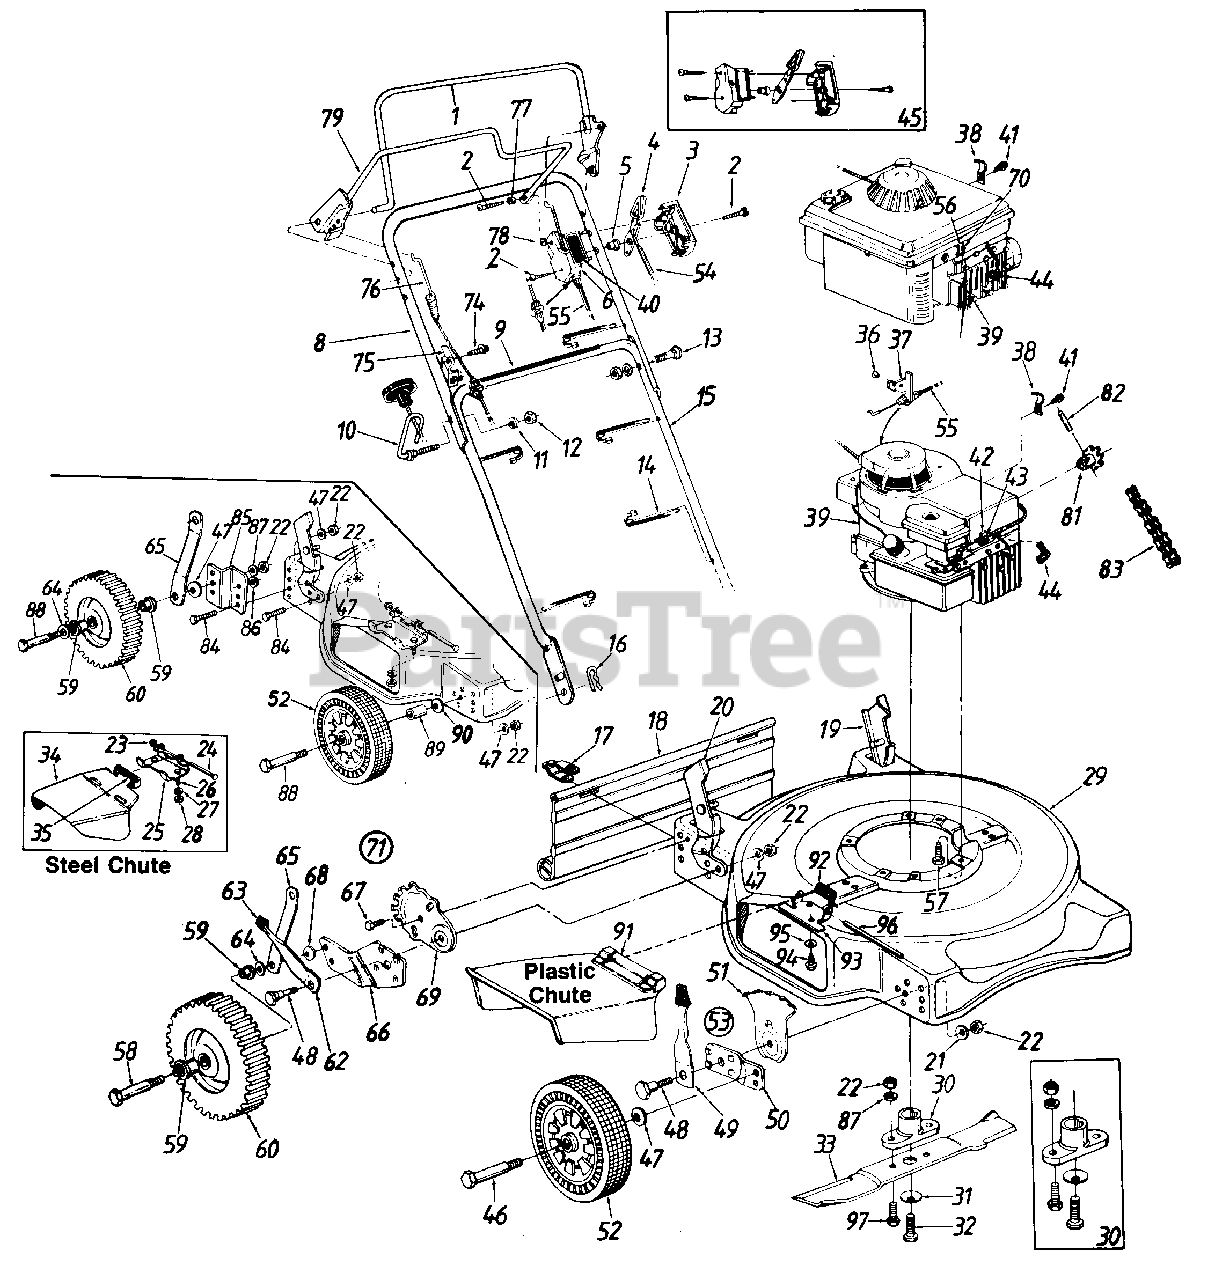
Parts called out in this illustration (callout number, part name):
1	Control Handle Ass'y.
2	Truss Mach. Scr. #12 x 1.5'
3	Control Panel Half
4	Throttle Control Lever
5	Control Disc Pin
6	Clutch Panel Half
8	Upper Handle (Painted)
9	Instruction Label-Handle
10	Rope Guide Bolt
11	L-Wash. 5/16" I.D.
12	Hex Nut 5/16-18 Thd.
13	Curved Carriage Bolt 5/16-18 x 1.38" Lg.
14	Cable Tie
15	Lower Handle (Painted)
16	Hairpin Cotter
17	Hinge Clip
18	Rear Flap
19	Handle Bracket Ass'y.-L.H.
20	Handle Bracket Ass'y.-R.H.
21	Bell-Wash. .39" I.D. x 1.38"
22	Hex Nut 3/8-16 Thd.
23	Push Cap 1/4" Rod
24	Pivot Pin
25	Adapter Plate
26	Hex Bolt 1/4-20 x .50" Lg.
27	L-Wash. 1/4" I.D.
28	Hex Nut 1/4-20 Thd.
29	22" Deck Ass'y.
30	Blade Adapter Kit
31	Bell-Wash. .39" I.D. x 1.12" O.D.
32	Hex Bolt 3/8-24 x 1.5" Lg.
33	22n Blade
34	Chute Deflector Ass y.
35	Torsion Spring
36	Pop Rivet
37	Cable Bracket
38	Cable Clamp
39	Engine
40	Throttle Label
41	Hex B-Tap Scr. #10 x .38"
42	Cable Clamp
43	Hex AB-Tap Scr. #8 x 88n Lg.
44	Spark Plug Boot
45	Kit-Control Housing Comp.
46	Front Axle Bolt
47	Bell-Wash. .400" I.D. x .881'
48	Shld. Bolt .50" Dia. x .357"
49	Spring Lever Ass'y. w/Knob
51	Height Adj. Plate
52	Wheel Ass'y. Comp.
53	Height Adj. Ass'y. Comp.-R.H.
54	Throttle Wire-53"
55	Control Cable-39"
56	Cable Clamp
57	Hex L-Wash. HD. Scr. 3/8-16 x 1.0" Lg.
58	Rear Axle Bolt
59	Fl. Ball Brg. 1/2" I.D.
60	Rear Wheel Ass'y. Comp.
62	Spring Lever
63	Spring Lever Knob
64	Fl-Wash. .531" I.D. x .93"
67	Hex AB-Tap 1/4-.62" Lg.
68	Bell-Wash. .380" I.D. x .88"
69	Index Plate
70	Hex B-Tap Scr. #10 x .62"
71	Rear Height Adj. Ass'y.-R.H.
74	Hex Wash. AB-Tap Scr. 5/16 x.75" Lg.
75	Cable Brkt.
76	Clutch Cable w/Spring-33"
77	Spacer 23" I.D. x .30" O.D.
78	Spr.-Wash. .206" I.D. x .448
79	S.P. Bail Ass'y.
81	10 Tooth Sprocket Ass'y.
82	Spring Pin Spir. 3/16" Dia. x 1" Lg
83	#48 Chain 1/2" Pitch 50 Links (Endless)
84	Hex Bolt 3/8-16 x .75" Lg.
85	Wheel Bracket
86	Fl-Wash..385" I.D.
87	L-Wash. 3/8" I.D.
88	Shld. Bolt.498n Dia.
89	Spacer .511" I.D.
90	Bell-Wash. 39" I.D.
91	Chute Deflector Ass'y.
92	Torsion Spring
93	Adapter Plate
94	Hex Self-Tap Scr. 1/4-20 x .5" Lg.
95	Bell-Wash. 1/4" I.D.
96	Hinge Pin
97	Hex Bolt 3/8-16 x 1 " Lg.
